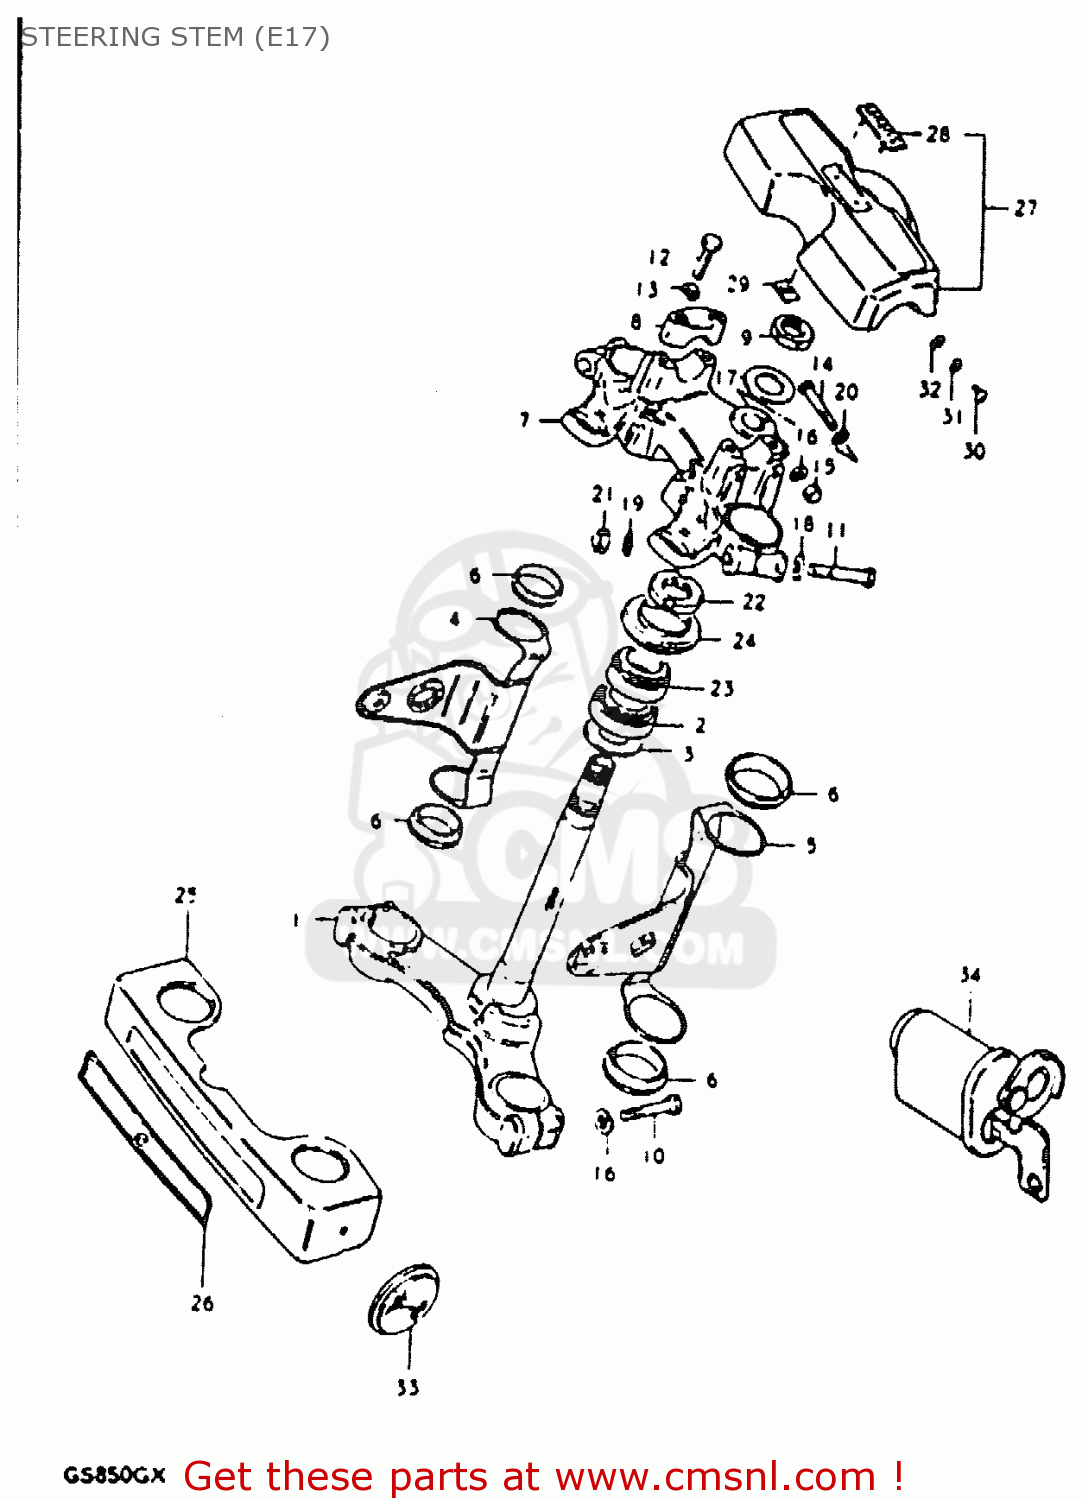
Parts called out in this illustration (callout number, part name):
1	STEM,STEERING
2	BEARING
3	WASHER,THRUST
4	BRACKET,HEADLAMP,RIGHT
5	BRACKET,HEADLAMP,LEFT
6	CUSHION,HEADLAMP BRACKET
7	HEAD,STEERING STEM
8	HOLDER,HANDLE(BLACK)
9	NUT,FR FORK UPR BRACKET
10	BOLT
11	BOLT 10X55
12	BOLT
13	LOCK WASHER
14	BOLT 8X50
15	NUT
16	LOCK WASHER
17	WASHER
18	WASHER
19	LOCK WASHER
20	WASHER
21	NUT, LOWER LH
22	NUT,STEERING STEM(25X44X10)
23	TAPER,ROLLER BEARING
24	DUST SEAL,STEERING,UPPER
25	COVER,FRONT FORK
26	EMBLEM
27	PAD,HANDLEBAR
28	EMBLEM,HANDLE COVER PAD
29	NUT
30	SCREW
31	LOCK WASHER
32	WASHER
33	REFLEX REFLECTOR,RR
34	LOCK ASSY, STEERING (NEIMAN TYPE EXECUTE
